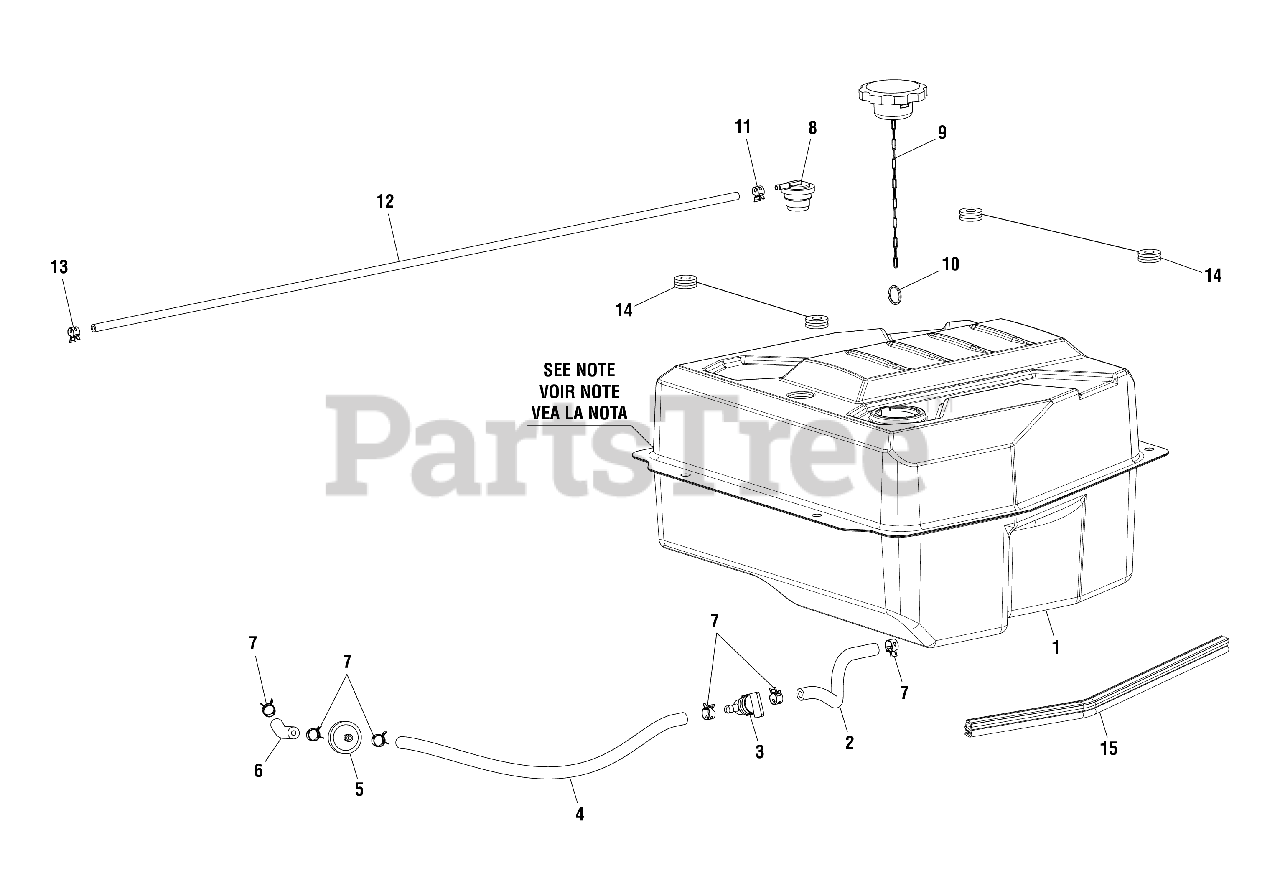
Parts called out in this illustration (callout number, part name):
1	FUEL TANK 8 GALLON W/ BUSHINGS/SPACERS
2	FUEL HOSE, 220MM X 1/4IN
3	FUEL SHUT OFF VALVE 180 DEGREE
4	FUEL HOSE, 1/4 X 390MM
5	Fuel Filter Inline (1/4 in.)
6	FUEL HOSE, 95MM X 5MM ID
7	Fuel Line Clamp (1/2 in.).
8	Fuel Tank Vent Valve (PS905055SA)
9	Fuel Cap Assembly
10	Ring Clip
11	Fuel Line Clamp (7/16 in., BM903611)
12	Vapor Hose (590 mm and 30 mm)
13	Fuel Line Clamp (10.3 mm)
14	Bushing w/Insert
15	BONDED RUBBER, WEATHER STRIPPING
